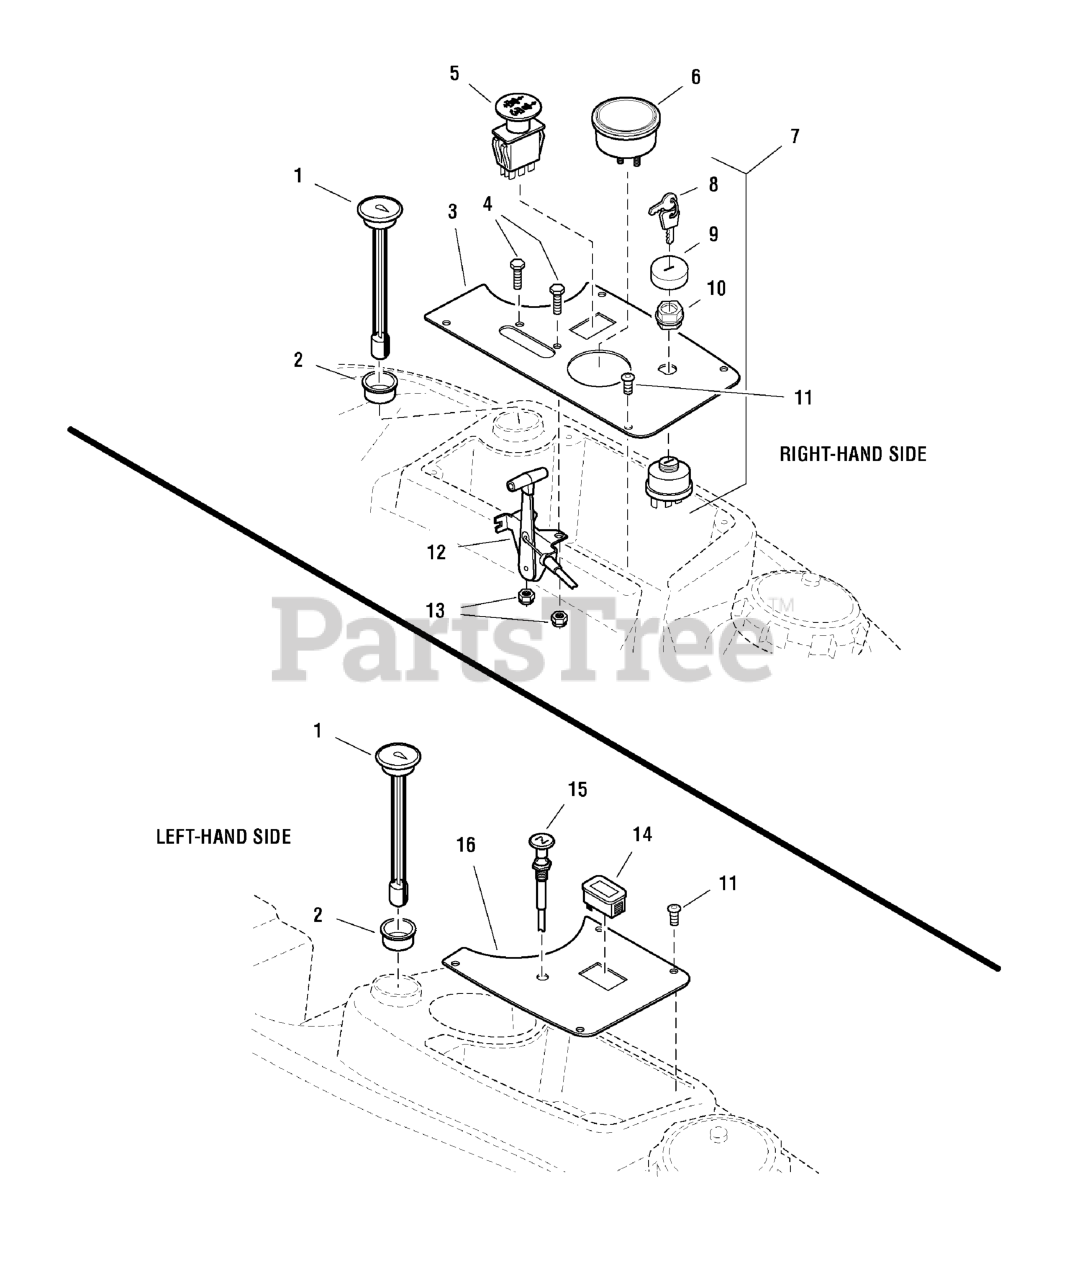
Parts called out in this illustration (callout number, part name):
1	GAUGE, FUEL, 12
2	GROMMET
3	CONTROL PANEL-RH
4	BOLT, 1/4-20 x 3/4
5	SWITCH, BLADE ENGAGEMENT
6	TEMPERATURE GAUGE
7	SWITCH, IGNITION, 6 POST
8	KEY, IGNITION MOLDED SET
9	COVER, PLASTIC, SNAP ON
10	PLASTIC NUT
11	SCREW, Allen Head, 1/4-20 x 1/2
12	CABLE, Throttle, 45"
13	NUT, 1/4-20 HEX SERR. FLANGE
14	HOUR METER
15	CABLE, CHOKE CONTROL, 56", DETENTED
16	CONTROL PANEL-LH
